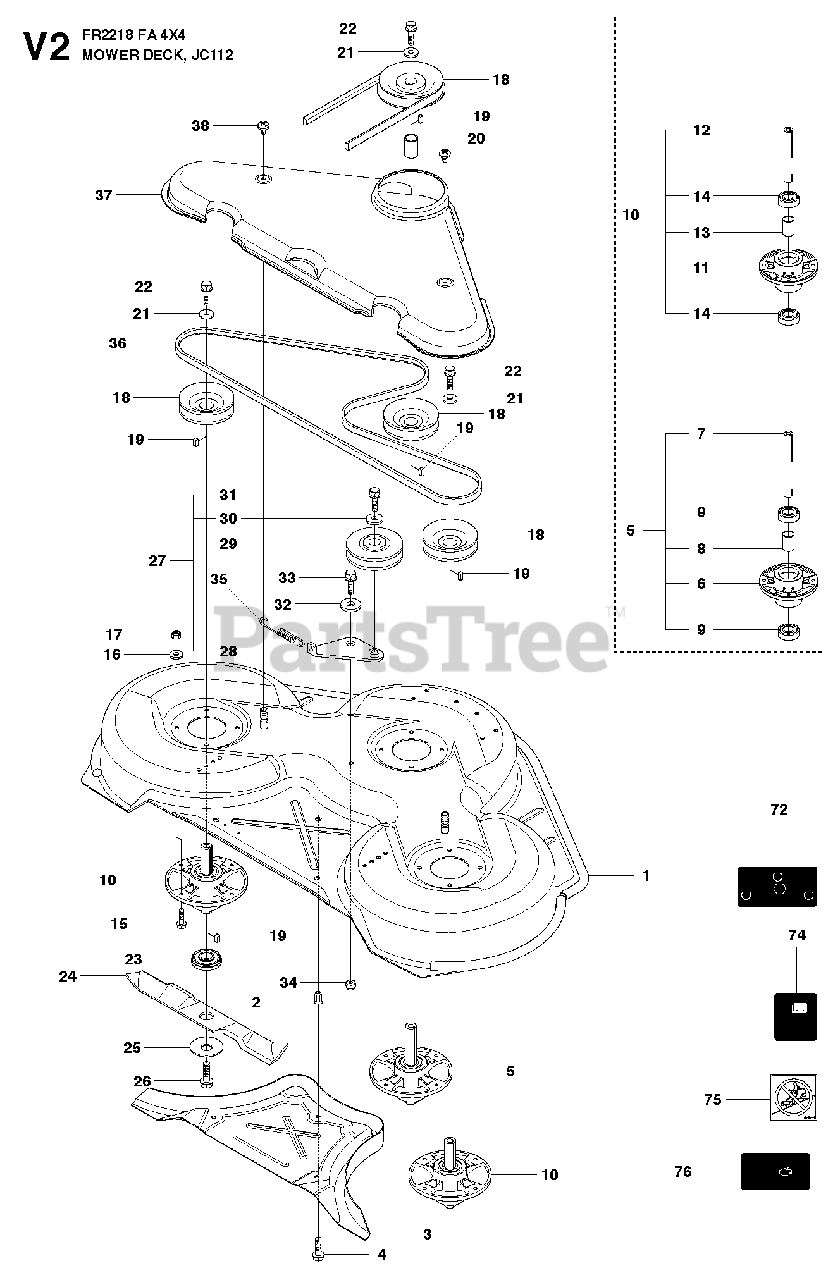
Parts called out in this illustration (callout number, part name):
5	RP SPINDLE ASSY
6	BEARING HOUSING
7	SHAFT
8	SPACER
9	BEARING
10	RP SPINDLE ASSY
11	BEARING HOUSING
12	AXLE
13	SPACER
14	BEARING
16	WASHER BRB 8.4X17
17	LOCKNUT M8
24	BLADE
25	WASHER
27	BELT TENSIONER ASSY
28	BELT TENSIONING ARM
29	PULLEY
30	SPACER
31	BOLT
32	WASHER
34	LOCKNUT M8
36	BELT
